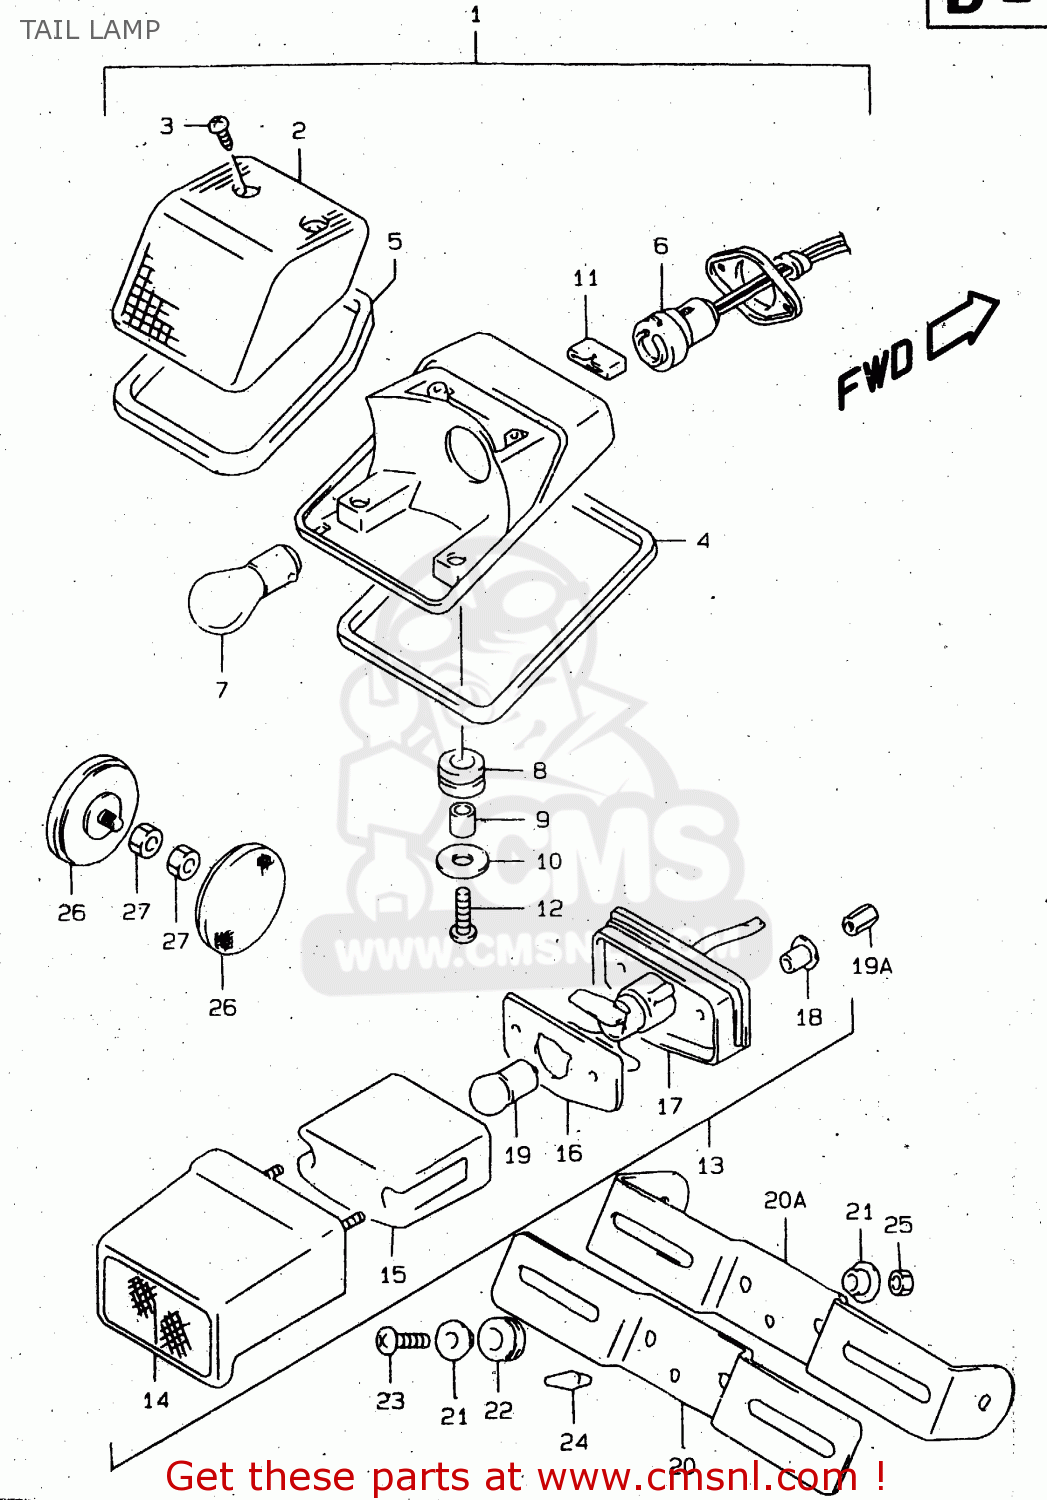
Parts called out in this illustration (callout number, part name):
1	LAMP ASSY,REAR
2	LENS
3	SCREW
4	GASKET
5	GASKET
6	SOCKET & CORD
7	BULB(12V21/5W)
8	CUSHION
9	SPACER(6.5X9X12.5)
10	WASHER(6.5X20X1.6)
11	CUSHION
12	SCREW, 6X20
13	LAMP ASSY,LICENSE
14	COVER,LENS
15	LENS
16	GASKET,LICENSE LAMP (NAS)
17	CUSHION
18	SPACER
19	BULB(12V5W,BF150-40160A)
19A	NUT
20	BRACKET,LICENSE PLATE
20A	BRACKET,LICENSE PLATE
21	WASHER
22	CUSHION
23	SCREW
24	CUSHION
25	NUT 6MM
26	REFLECTOR,REFLEX
27	NUT
